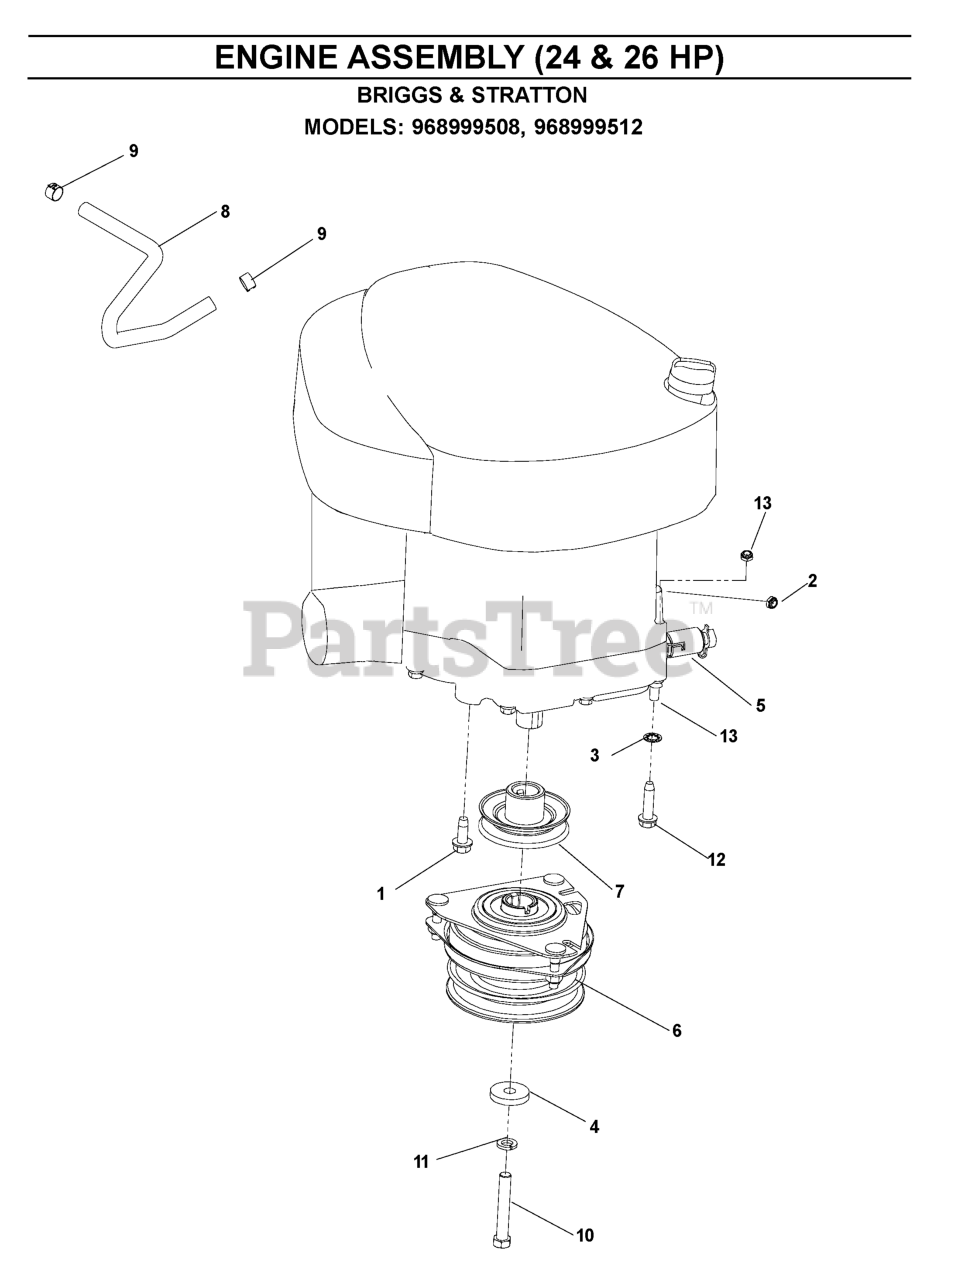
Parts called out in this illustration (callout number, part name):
1	BOLT 3/8-16 X 1.0
2	JAM NUT 1/4C (2 2 PW01)
3	WASHER 5/16 FLAT
4	CLUTCH, WASHER
5	OIL DRAIN FITTING
6	RB.CLUTCH.OGURA.4.4.PD
8	FUEL LINE 5"
9	HOSE CLAMP
10	HEX SCREW 7/16-20 X 3
11	WASHER 7/16 LOCK
13	NUT 3/8C CENTERBLOCK
